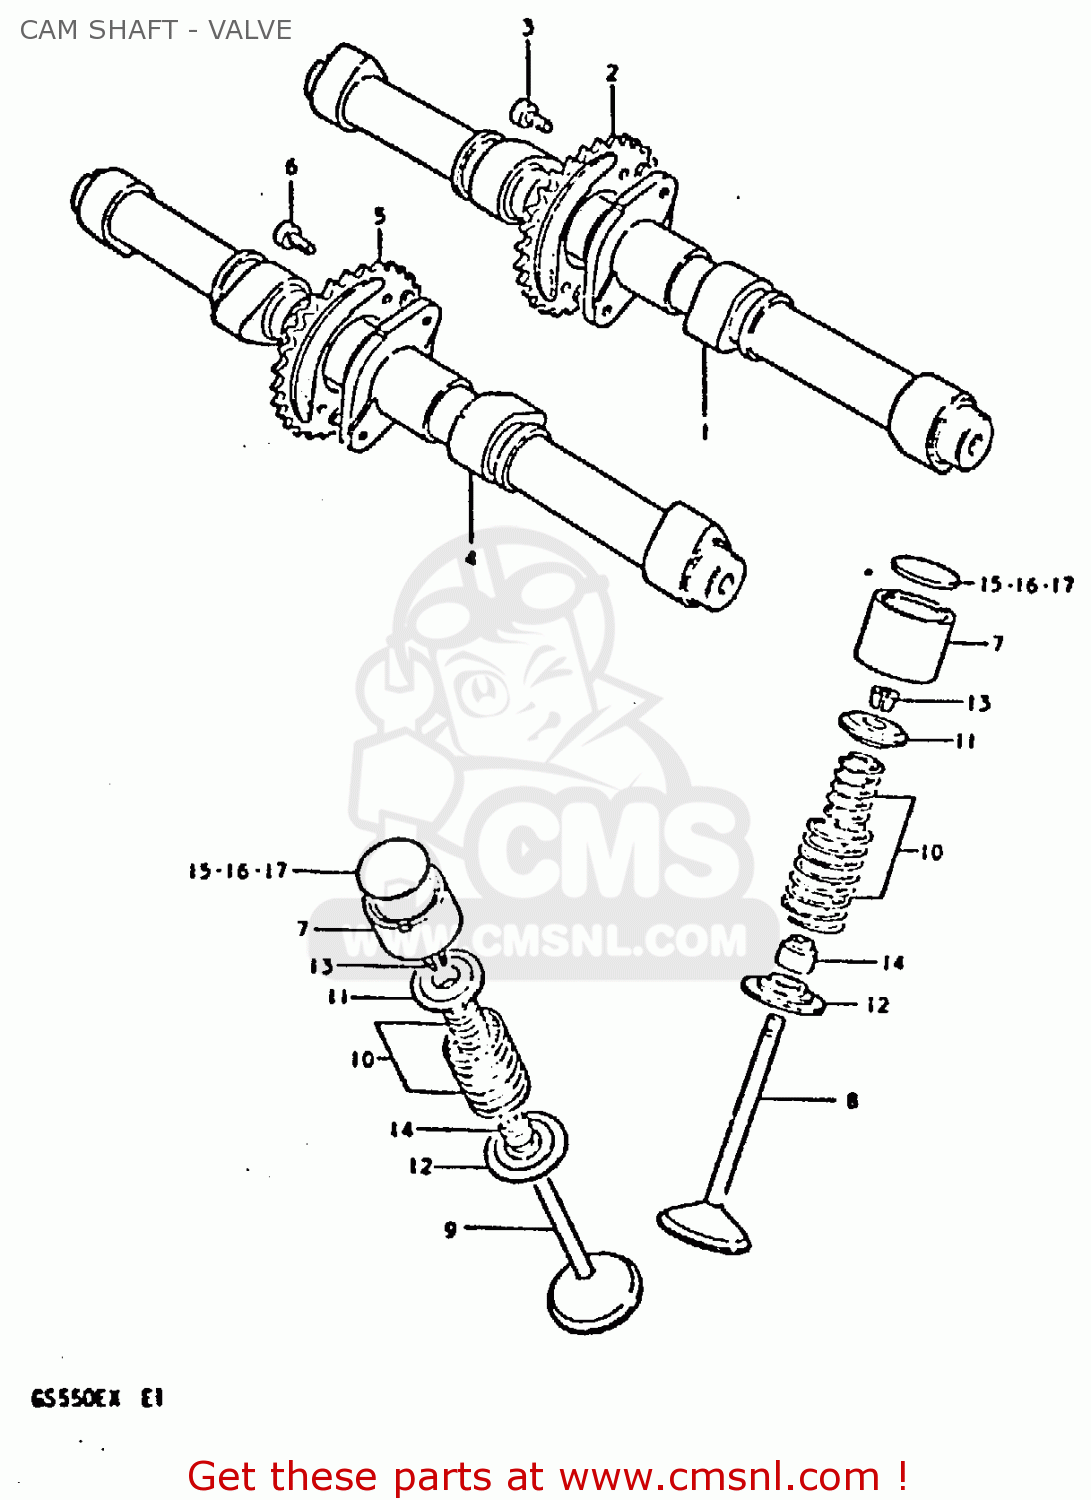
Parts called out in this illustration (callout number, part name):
1	CAMSHAFT
2	SPROCKET,CAMSHAFT
3	BOLT 6X11
4	CAMSHAFT,EXHAUST
5	SPROCKET,EXHAUST CAMSHAFT
6	BOLT 6X11
7	TAPPET
8	VALVE,INTAKE
9	VALVE,EXHAUST
10	SPRING SET,VALVE
11	RETAINER,VALVE SPRING
12	SEAT,VALVE SPRING
13	COTTER VALVE
14	SEAL,OIL(7X14.4X9)
15	SHIM,TAPPET
16	SHIM,TAPPET
17	SHIM,TAPPET
